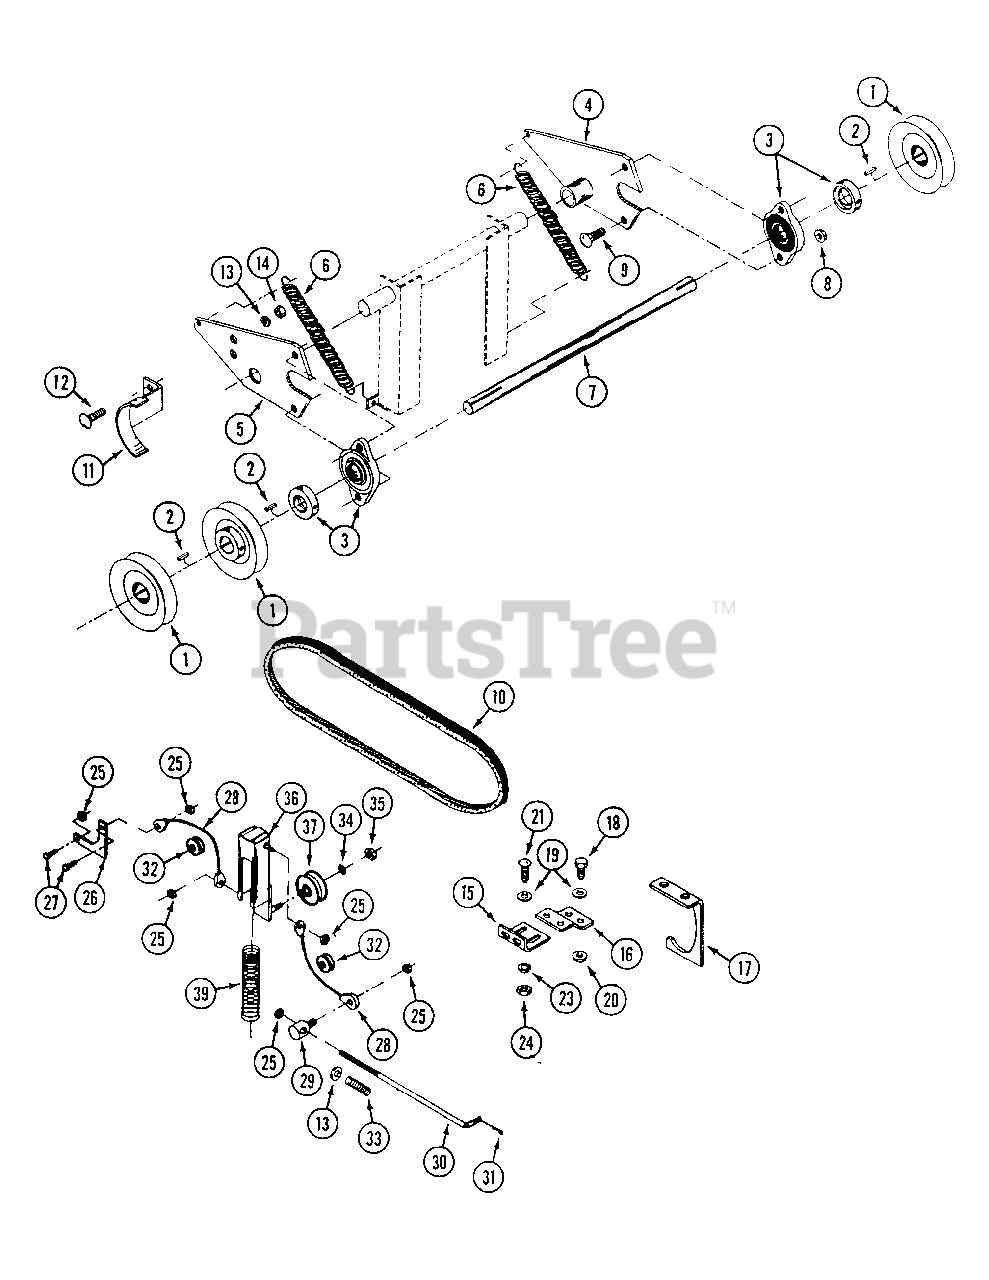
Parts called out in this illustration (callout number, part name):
1	PULLEY - 4" O.D. x 3/4" ID
2	KEY - 3/16" x 3/16" x 1"
3	BEARING - flanged
4	MOUNT - bearing L.H.
5	MOUNT - bearing R.H.
6	SPRING -extention
7	SHAFT - cross
8	NUT - 5/16 - 18 flange lock
9	BOLT - 5/16" - 18 x 1" carriage
11	RETAINER - cross shaft belt
12	BOLT - 1/4" - 20 x 3/4" carriage
13	WASHER - 1/4"
14	NUT - 1/4" - 20 flange lock
15	BRACKET - engine belt retainer
16	BRACKET - engine belt
17	RETAINER - engine belt
18	BOLT - 1/4" - 20 x 3/4"
20	NUT - 1/4" - 20 flange lock
21	BOLT - 1/4" - 20 x 1" carriage
23	LOCKWASHER - 1/4"
24	NUT - 1/4" - 20
25	NUT - nylock 1/4" - 20
26	BRACKET - "L", brake linkage
27	BOLT - 1/4" - 20 x 1"
28	CABLE - clutch, brake
29	COLLAR - caliper rod
31	PIN - cotter - 3/32" x 1"
32	PULLEY - 1-1/2" O.D.
33	SPRING - caliper rod
34	LOCKWASHER - 3/8"
35	NUT - 3/8" - 16
36	TUBE - drive idler
37	PULLEY - idler 2-1/4" O.D.
39	SPRING - belt tightener
